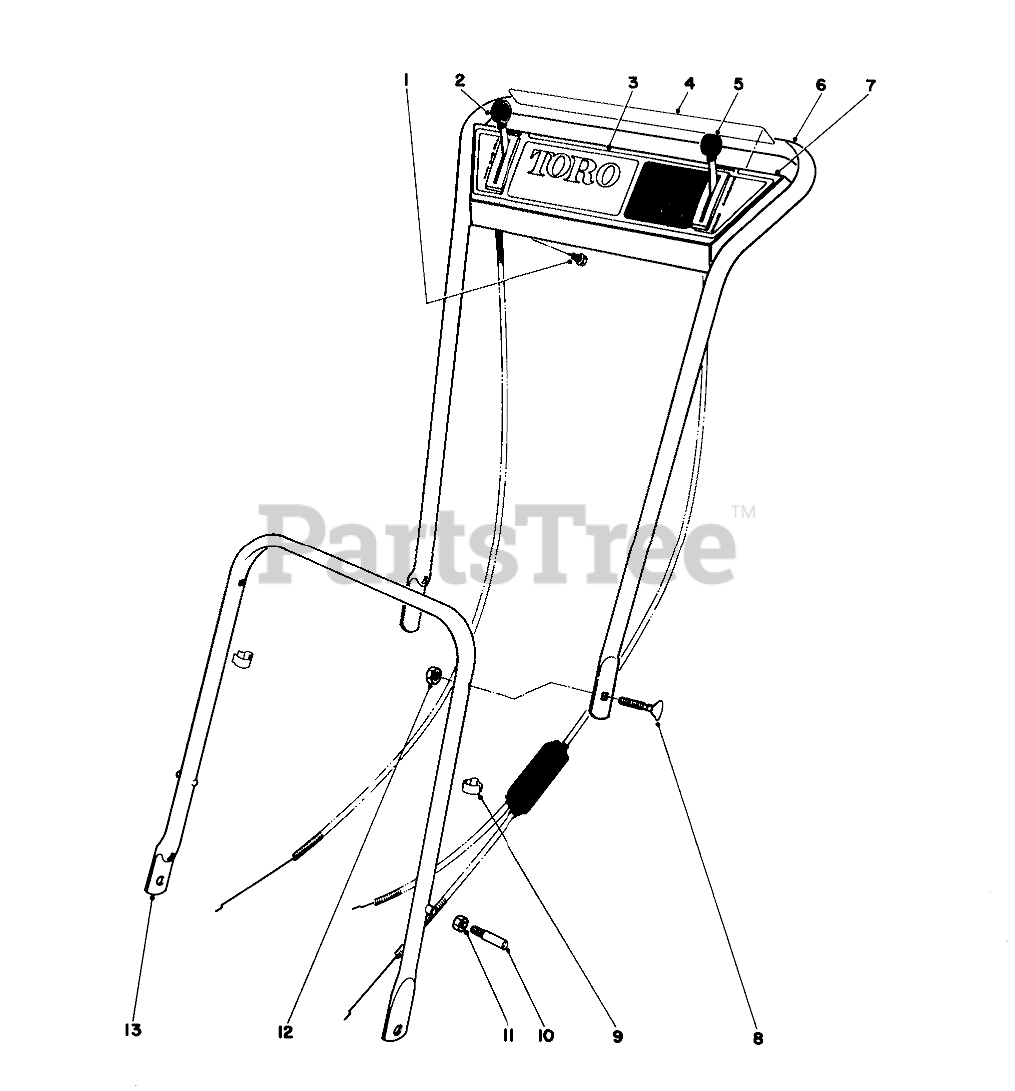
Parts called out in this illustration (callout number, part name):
1	SCREW-HWHTF
2	Throttle Control
3	Decal Escutcheon Plate (Model No. 16273)
4	Decal Safety Instructions
5	Traction Control (Model No.16273)
6	UPPER HANDLE
7	Escutcheon Plate (Model No.16273)
8	SCREW-HANDLE
10	HANDLE PIN
11	Nut
12	Nut
13	LOWER HDLE STKD ASM
